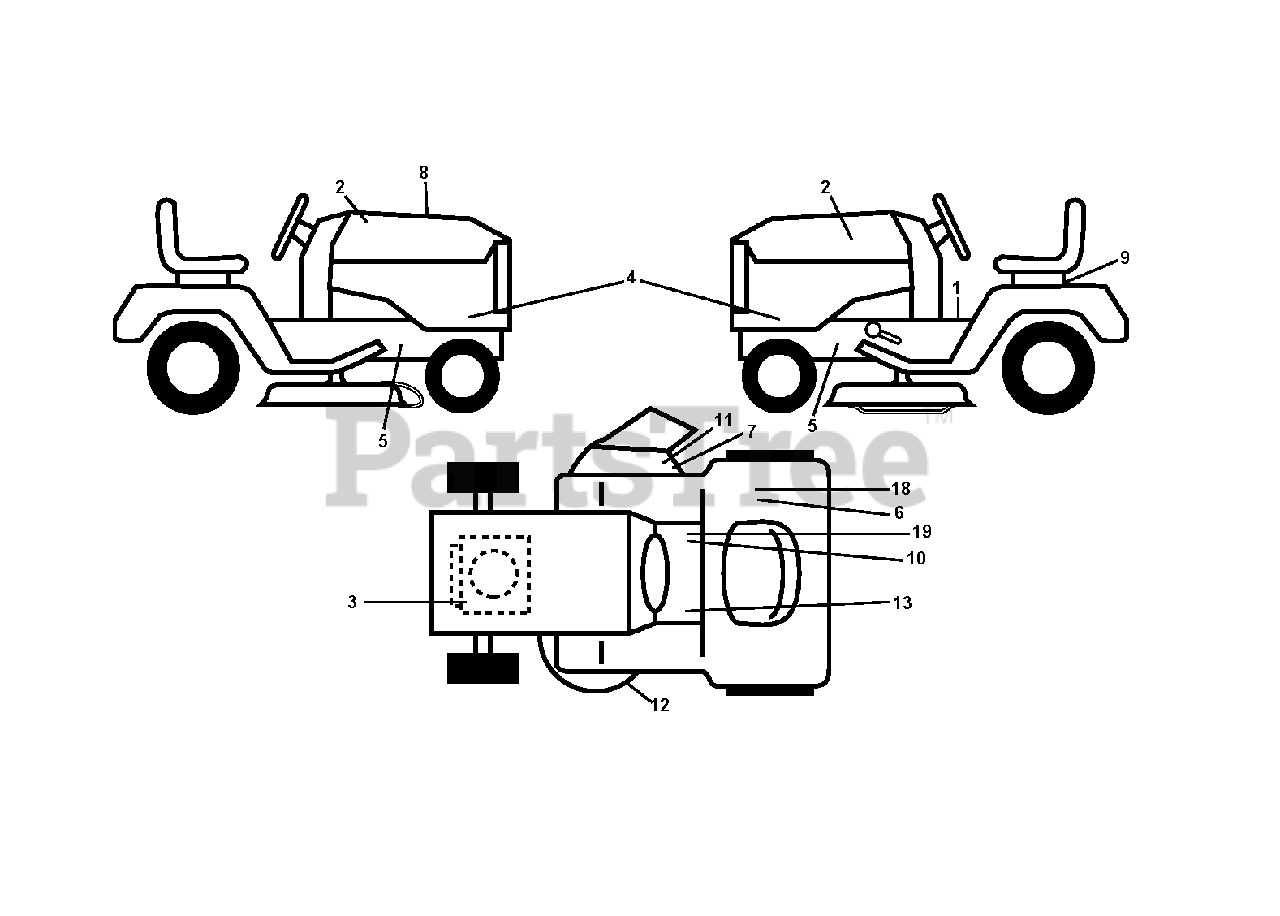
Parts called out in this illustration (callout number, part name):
1	LABEL
2	RP.DECAL.BADGE.170MM.TEXTLOGO
3	DECAL
4	DECAL.SIDE.PANEL.LTH2038
6	DECAL 80 DBA
7	DECAL, DEFLECT WARNING
8	DECAL DECAL.RPL.BSM33.ENDU.TLW
9	DECAL BTRY SYMBOLS
10	DECAL PARK BRAKE
11	DECAL.INTERNATIONL.CUTFINGER
12	DECAL.V-BELT.SCHEMATIC.36/38/9
13	DECAL
18	DECAL
19	DECAL
